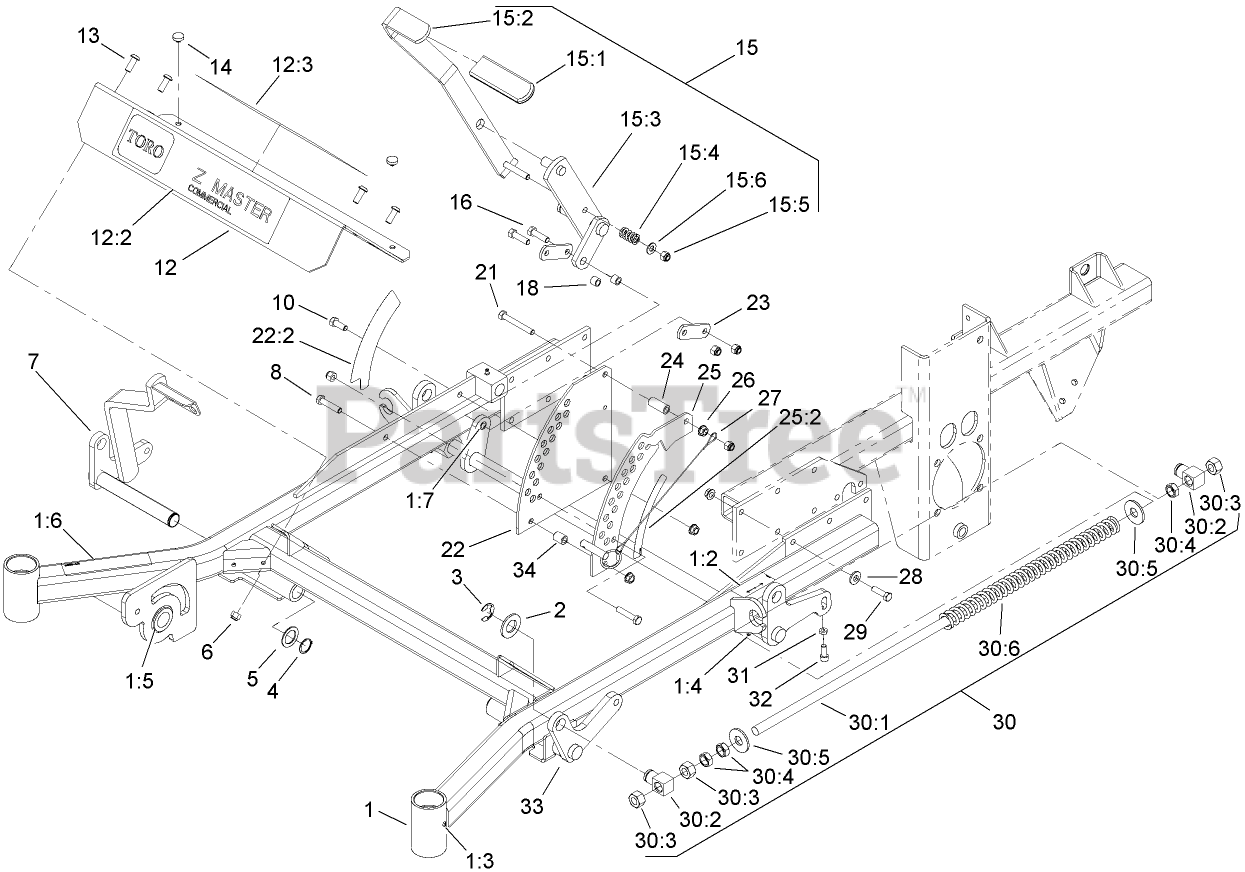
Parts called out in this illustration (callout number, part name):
1	FRAME ASM
1:2	Decal-Brake, Parking
1:4	FITTING-GREASE
1:5	BUSHING
1:6	DECAL-WARNING
1:7	Bushing
2	WASHER-FLAT
3	RING-RETAINING, EXT
4	RING-RETAINING
5	WASHER-SPACER
6	NUT-LOCK, NI
7	LIFT-DECK, RH FRONT
8	SCREW-HH
10	SCREW-HH
12	FOOTREST
12:3	DECAL-WARNING
13	SCREW-HSBH
14	BUMPER
15	DECK LIFT HANDLE ASM
15:1	GRIP-LEVER, LIFT
15:2	LEVER-LIFT
15:3	ARM-LIFT, DECK
15:4	SPRING-COMPRESSION
15:5	NUT-LOCK, NI
15:6	WASHER-FLAT
16	SCREW-HH
18	Bushing
21	SCREW-HH
22	PLATE-DECK LIFT, OUTER
22:2	Decal-Height, Deck
23	ARM-LIFT, DECK
24	BUSHING-LEVER, LIFT
25	PLATE-DECK LIFT, INNER
25:2	Decal-Height, Deck
26	NUT-HHF, WHIZ
27	Hitch Pin ASM
28	WASHER-BELLEVILLE
29	SCREW-HH
30	Front Frame Spring ASM
30:1	ROD-LIFT, DECK
30:2	SWIVEL-DECK MOUNT, REAR
30:3	NUT-HEX
30:4	NUT-JAM
30:5	WASHER-FLAT
30:6	SPRING-SUPPORT, DECK
31	NUT-JAM
32	SCREW-HSH
33	LIFT-DECK, LH
34	BUSHING-LEVER, LIFT
